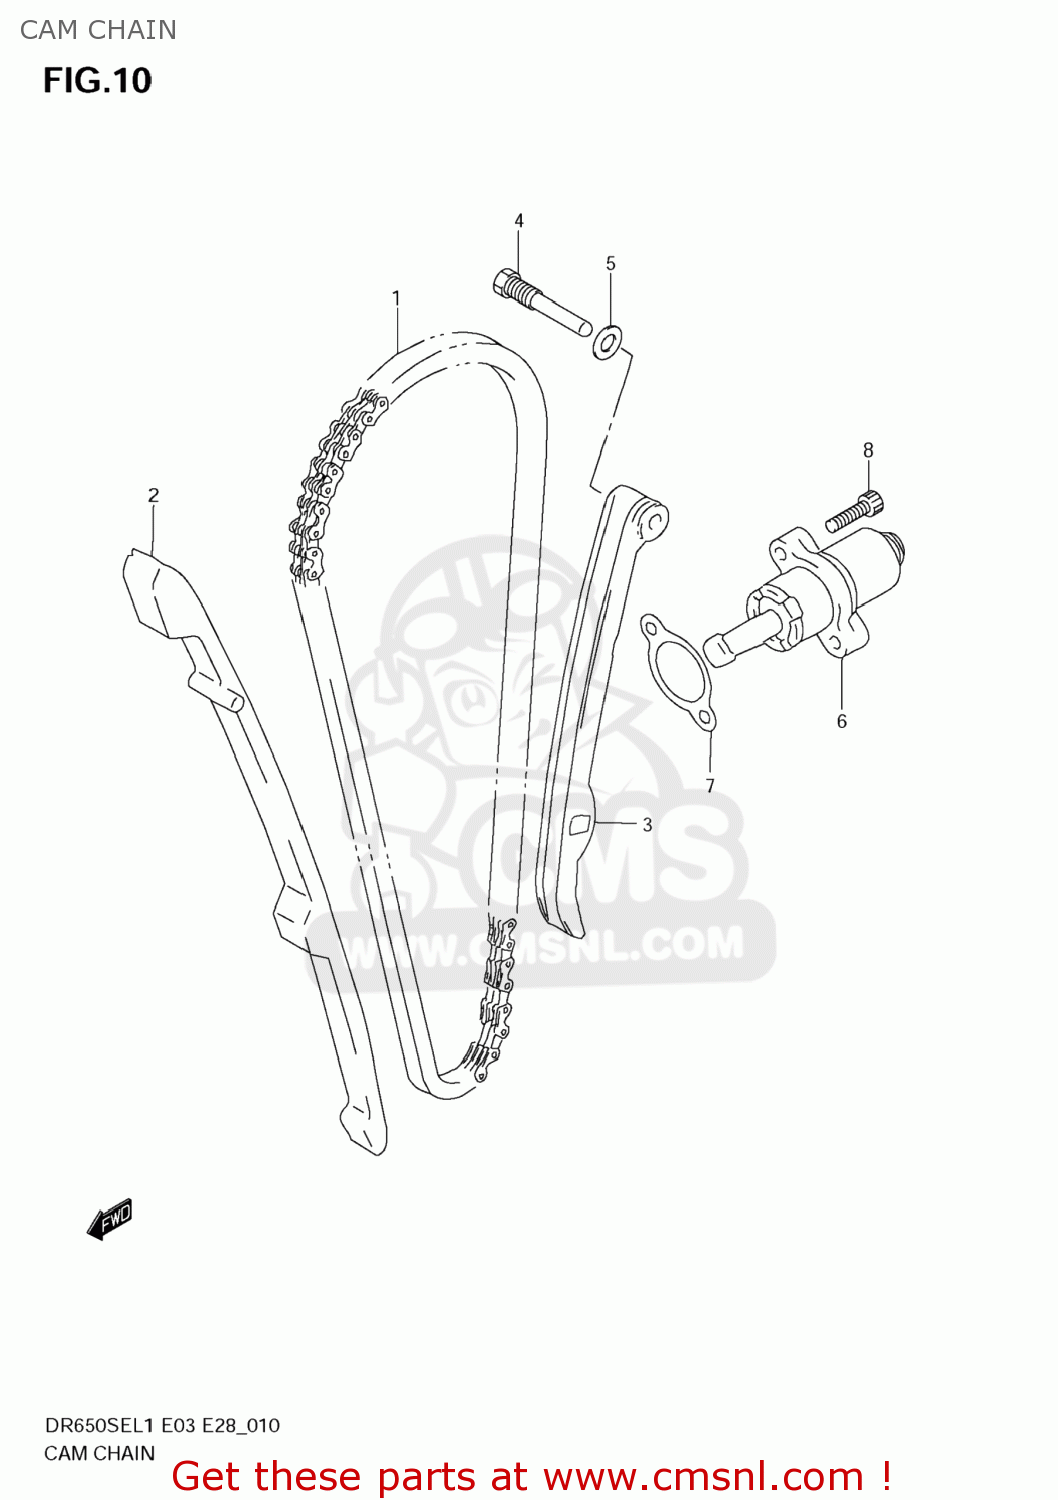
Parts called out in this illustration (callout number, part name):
1	CHAIN,CAMSHAFT DRIVE
2	GUIDE,CAM CHAIN
3	TENSIONER,CAM CHAIN
4	BOLT,CAM CHAIN TENSIONER
5	GASKET(8.2X14X1) (NAS)
6	ADJUSTER ASSY,TENSIONER
7	GASKET,TENSIONER ADJUSTER (NAS)
8	BOLT
